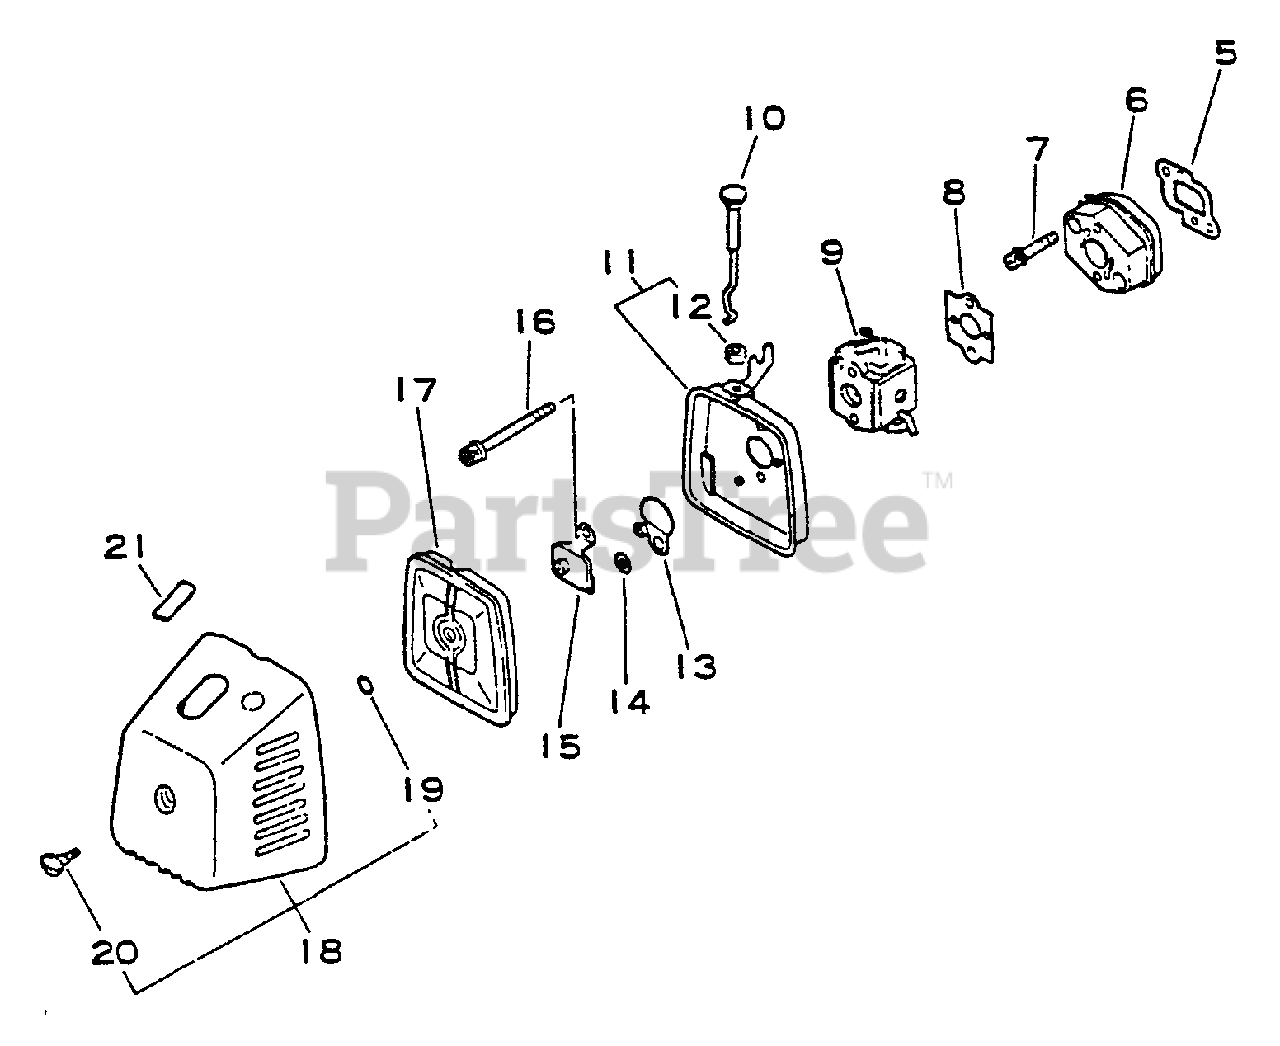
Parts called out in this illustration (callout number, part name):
5	GASKET, INTAKE
6	INSULATOR, INTAKE
7	BOLT 5×25
8	GASKET, INTAKE
9	CARBURETOR
10	ROD, CHOKE
11	CASE ASSY, AIR FILTER
12	GROMMET, CHOKE
13	SHUTTER, CHOKE
14	WASHER 5.2×8×0.8T
16	BOLT 5×57
17	FILTER, AIR
18	AIR FILTER COVER ASSY
21	LABEL - CHOKE
